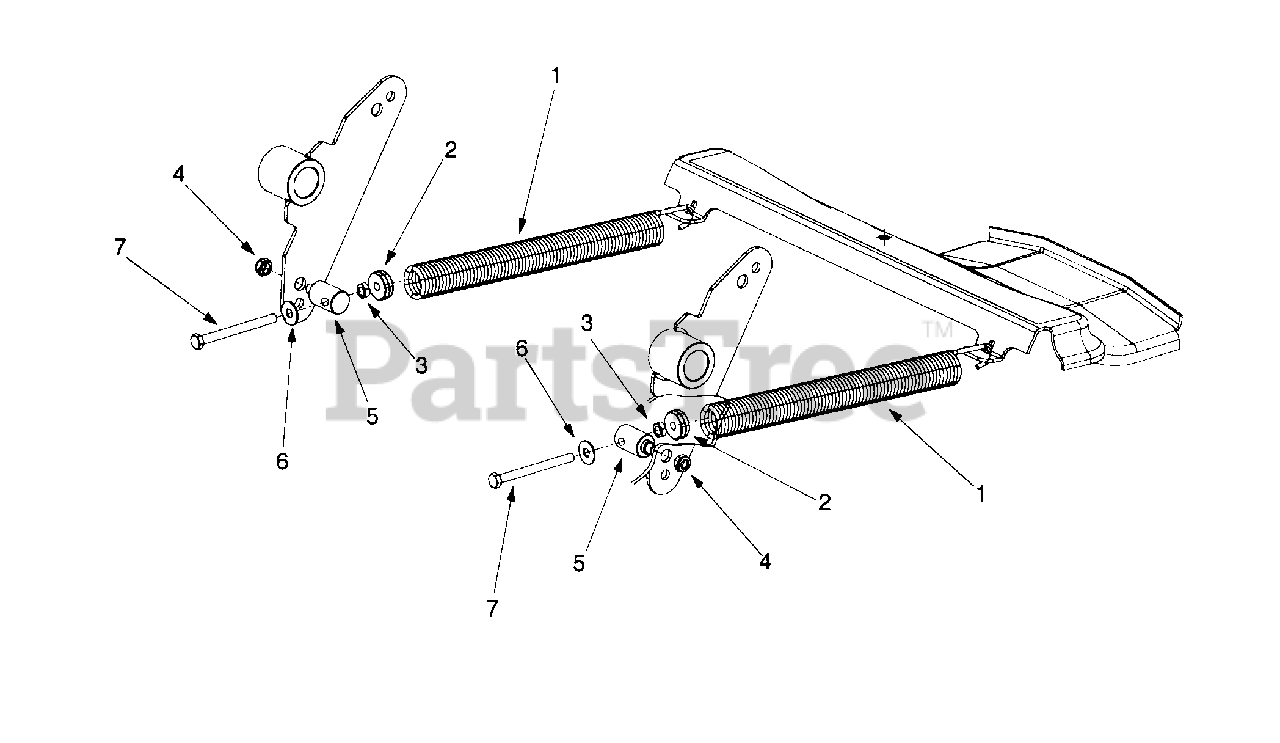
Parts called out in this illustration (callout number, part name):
1	Extension Spring 1.25 OD x 11.5 Lg
3	Hex Jam Nut 5/16-18
4	Jam Lock Nut 3/8-24
6	Washer 5/16
7	Hex Cap Screw 5/16-18 x 3.50
